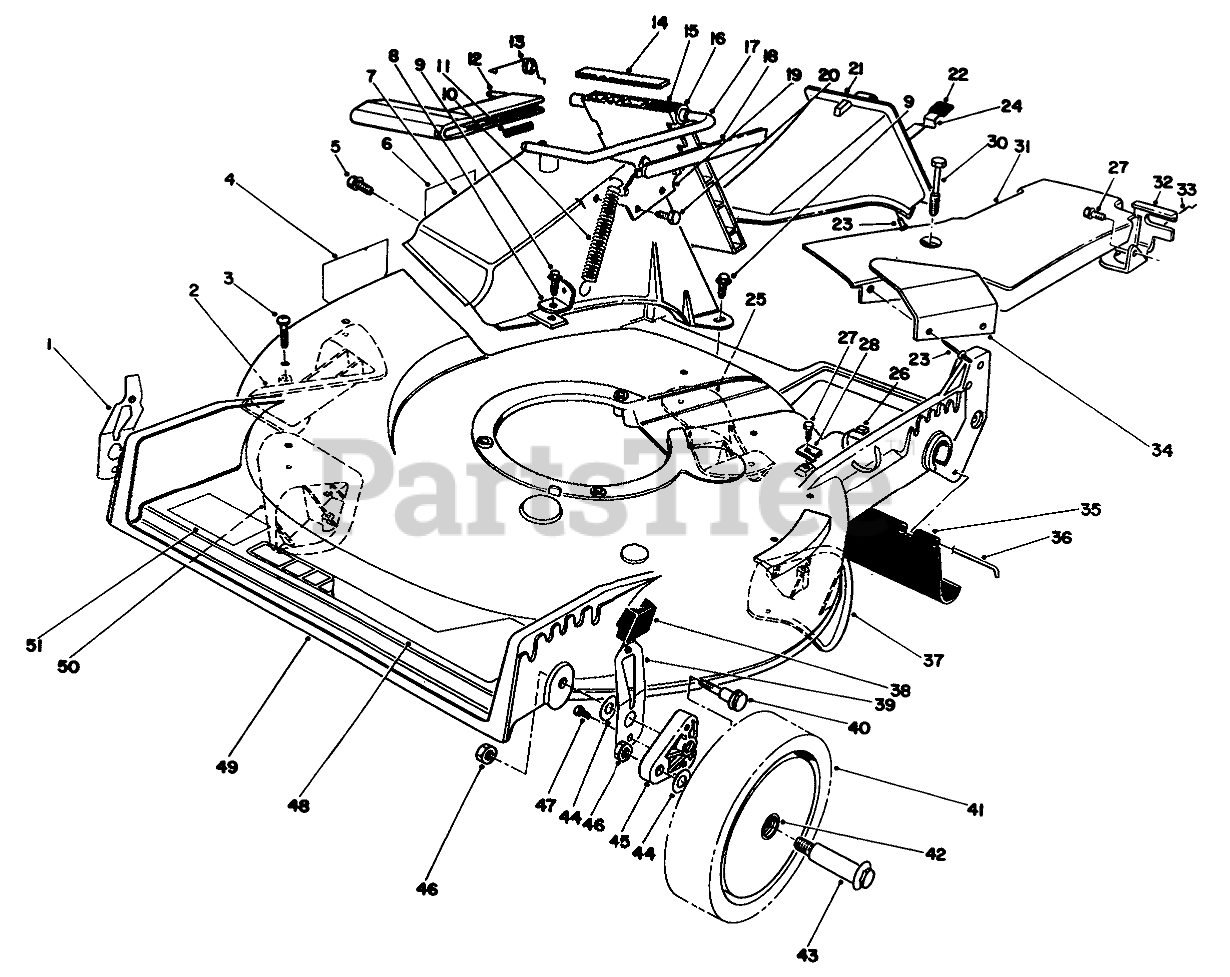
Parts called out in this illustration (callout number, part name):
1	RH SPRING ARM ASSEMBLY
2	KICKER
3	#8 X .625" PHILPS PAN H
4	DECAL-DANGER
5	SCREW AND WASHER ASM
6	DECAL - DANGER
7	DISCHARGE TUNNEL
8	Bracket-Spring
9	SCREW-HWH
10	SPRING-DOOR
11	Spring
12	Handle-Door
13	RETAINER-DOOR
14	Cover-Door
15	Door-Discharge
16	BUSHING-NYLON
17	Rod-Door
18	Cover-Handle
19	DOOR LATCH PLATE
20	SCREW-PLASTITE
21	Plug Assembly (Incl. Ref. #22-24)
22	GRIP-LATCH
23	RIVET-HEAD, FLAT
24	LATCH-PLUG, DISCHARGE
25	KICKER
26	TIE-CABLE
27	SCREW-HWHTF
28	CLAMP-CABLE
30	SCREW-HHFTF
31	Belt Cover Assembly (Incl. Ref. #23 & 34)
32	Bracket-Adj. Trac
33	RETAINER-CABLE
34	HEAT SHIELD
35	SHIELD-TRAILING
36	ROD-SHIELD
37	KICKER
38	KNOB-ARM
39	LH SPRING ARM ASSEMBLY
40	SCREW-SHOULDER
41	Wheel & Tire Assembly (Incl. Ref. #42)
42	BUSHING
43	WHEEL BOLT
44	WASHER
45	ARM-PIVOT, FRONT
46	Nut
47	SCREW-HWH
48	DECAL - DECK
49	Housing Assembly (Incl. Ref. #2-4, 25, 36 & 50))
50	KICKER
51	DECAL
